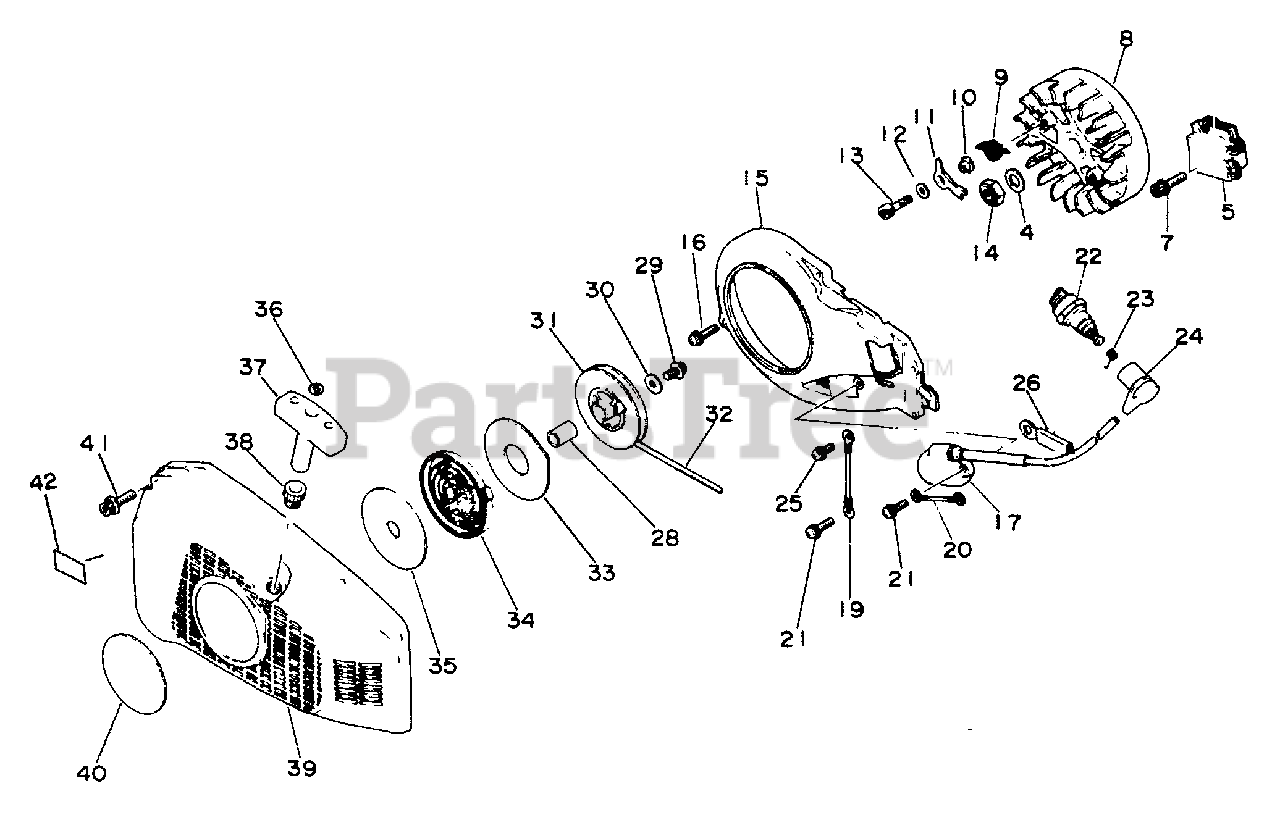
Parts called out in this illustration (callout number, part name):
5	COIL, IGNITION
7	BOLT 5×20
8	FLYWHEEL
10	SPACER
11	PAWL, STARTER
12	WASHER 5.5×12×0.8
13	BOLT 5×20
15	COVER, FAN
16	SCREW 4×20
17	COIL, IGNITION
19	LEAD
20	LEAD
21	SCREW 4×20
22	SPARK PLUG - BPM7A
23	TERMINAL, SPARK PLUG
24	CAP, SPARK PLUG
25	SCREW 4×12
29	SCREW 5×10
30	WASHER 5.2×16×1.0
31	REEL, ROPE
32	ROPE, STARTER 4.0×950
33	PLATE, SIDE
34	SPRING, RECOIL
35	PLATE, STARTER
38	GUIDE, ROPE
39	CASE, STARTER
40	LABEL - ECHO
41	BOLT 5×20
42	LABEL - NOISE
